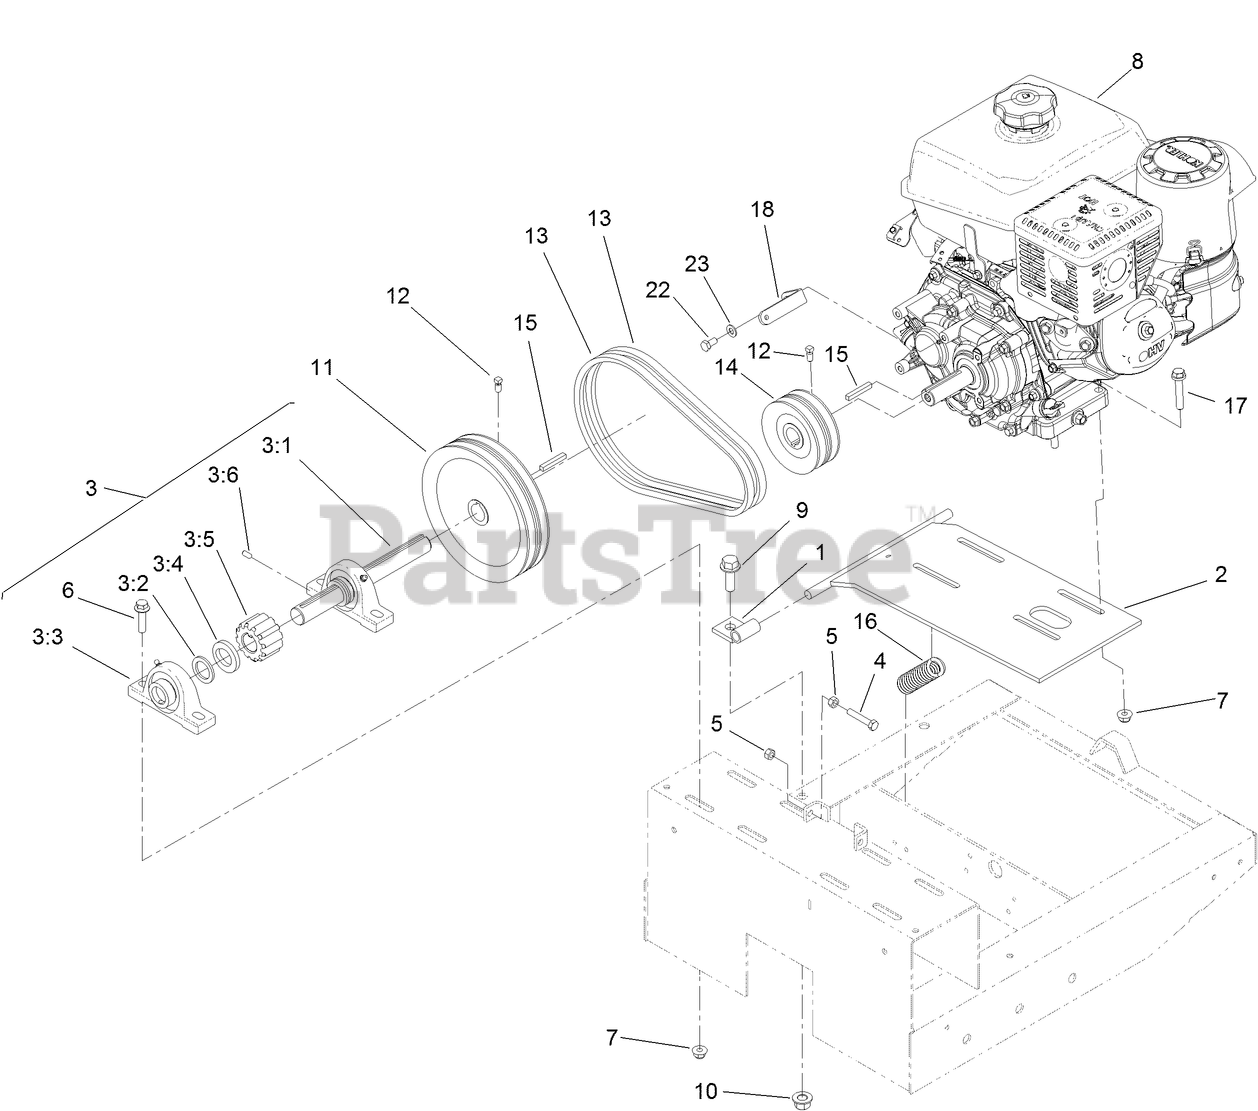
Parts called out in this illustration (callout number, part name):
1	MOUNT-MOTOR
2	BASE-MOTOR
3	PINION ASM
3:2	WASHER-THRUST
3:3	BEARING-BLOCK, PILLOW
3:4	WASHER
3:5	GEAR-SPUR
3:6	PIN-DOWEL
4	SCREW-HH
5	NUT-HEX
6	SCREW-HHF
7	NUT-HF, NI
8	ENGINE-KOHLER
9	SCREW-HHF
10	NUT-LOCK
11	SHEAVE
12	SCREW-SET
13	BELT-V
14	SHEAVE
15	KEY-SQUARE
16	SPRING
17	SCREW-HHF
18	GUIDE-BELT
22	SCREW-HH
23	WASHER-PLAIN
